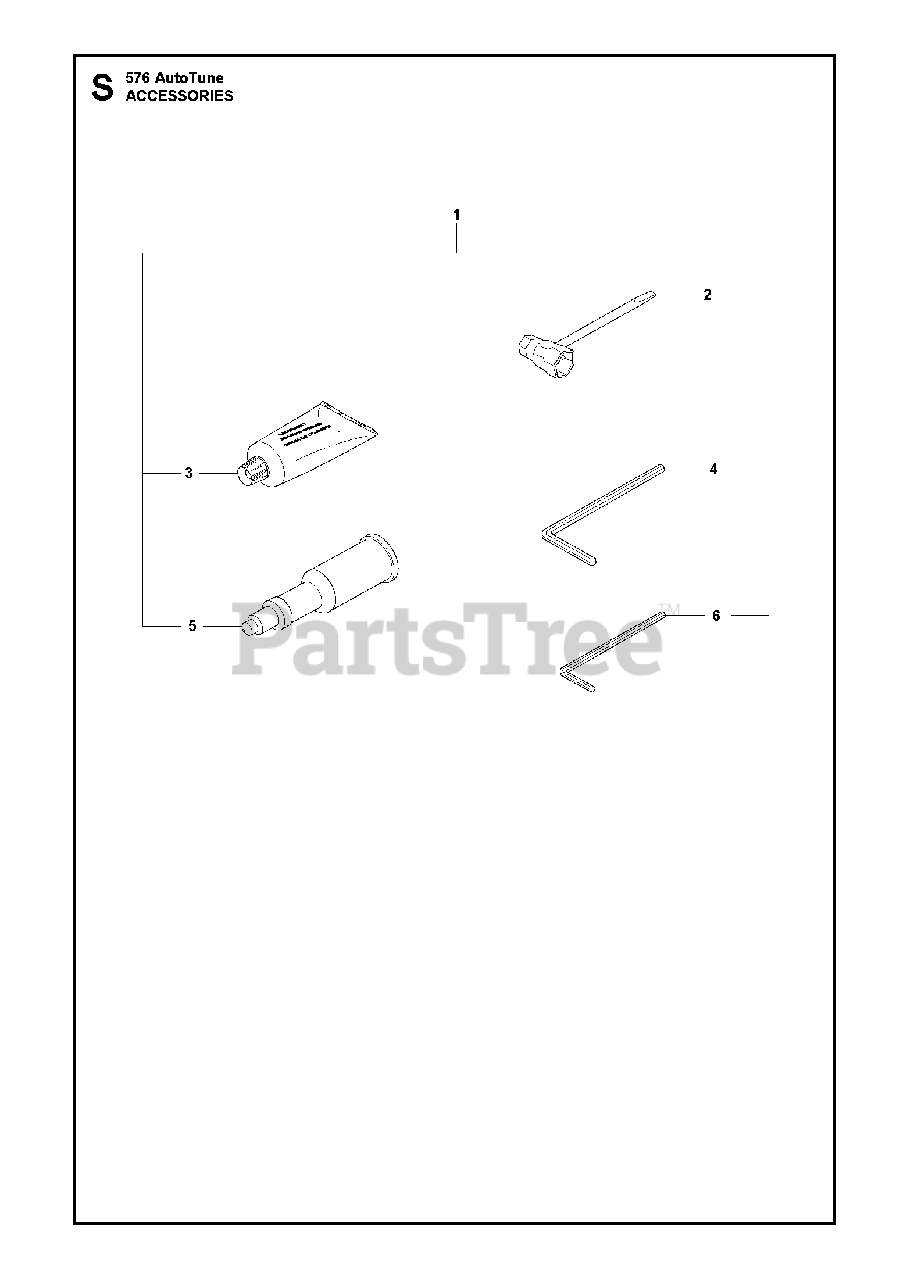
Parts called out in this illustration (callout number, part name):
1	TOOL KIT
2	COMBI TOOL
3	GREASE
4	L-SPANNER
5	Grease Gun
6	L-SPANNER
